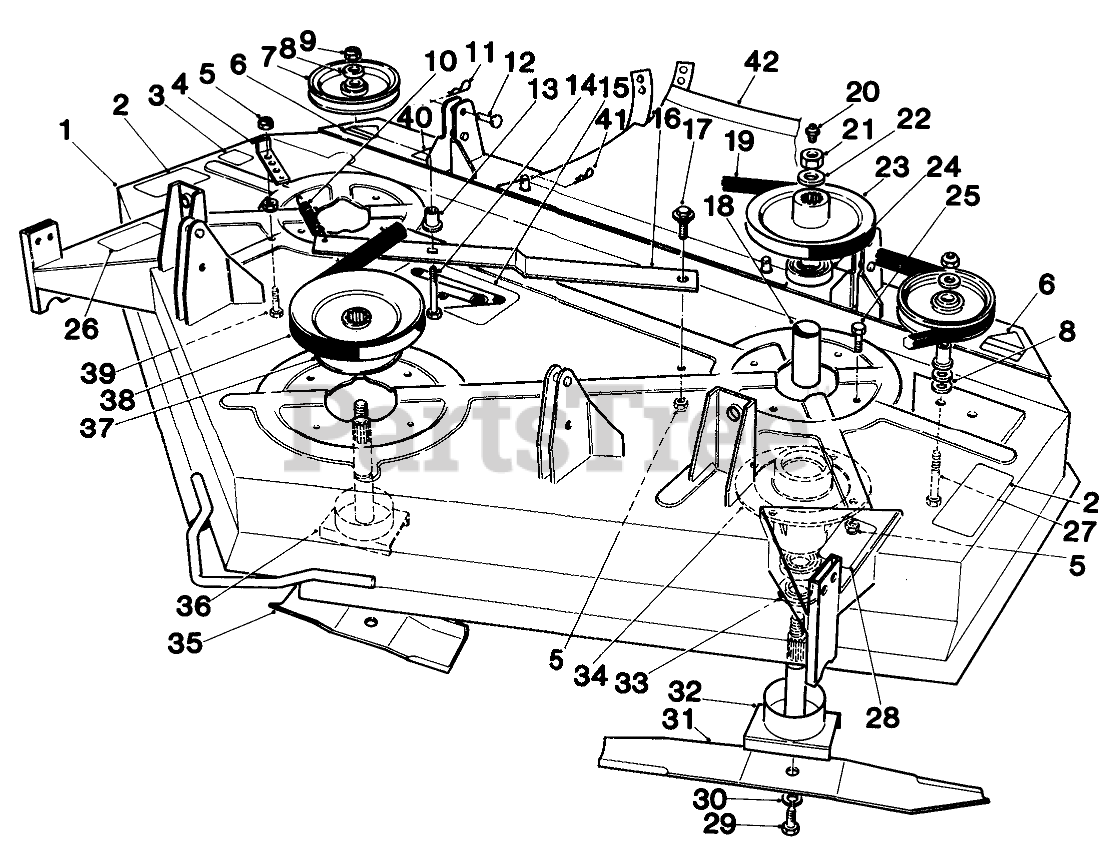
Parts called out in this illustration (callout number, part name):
1	DECK WA -48 RD H.M.R.R
2	DECAL - DANGER
3	SHAFT-GEAR, WORM
4	ANCHOR SPRING R
5	NUT-LOCK, NI
6	DECAL-DANGER
7	PULLEY-IDLER
8	WASHER-FLAT
9	NUT-LOCK, NI
10	SPRING-EXTENSION, DECK
11	Hair Pin-Cotter
12	PIN-CLEVIS
13	BUSHING-PULLEY
14	SCREW-HH
15	DECAL - BELT ROUTING
16	IDLER LEVER R
17	SCREW-SHOULDER
18	SPACER-BEARING
19	V BELT
20	FITTING-GREASE
21	NUT-HEX
22	WASHER
23	OUTSIDE PULLEY
24	BEARING-BALL
25	SCREW-HH
26	DECAL-TORQUE
27	SCREW-HH
28	DECAL - WHEEL ADJUSTMENT
29	SCREW-BLADE
30	WASHER-LOCK
31	L/H BLADE
32	SHAFT-SPINDLE
33	SPACER-SPINDLE
34	HOUSING-SPINDLE
35	CENTER BLADE
36	SHAFT-SPINDLE
37	CENTER PULLEY
38	V-BELT
39	SCREW-HH
40	DECAL-LEVEL, NOISE
41	PIN-COTTER
42	GRASS SHIELD
